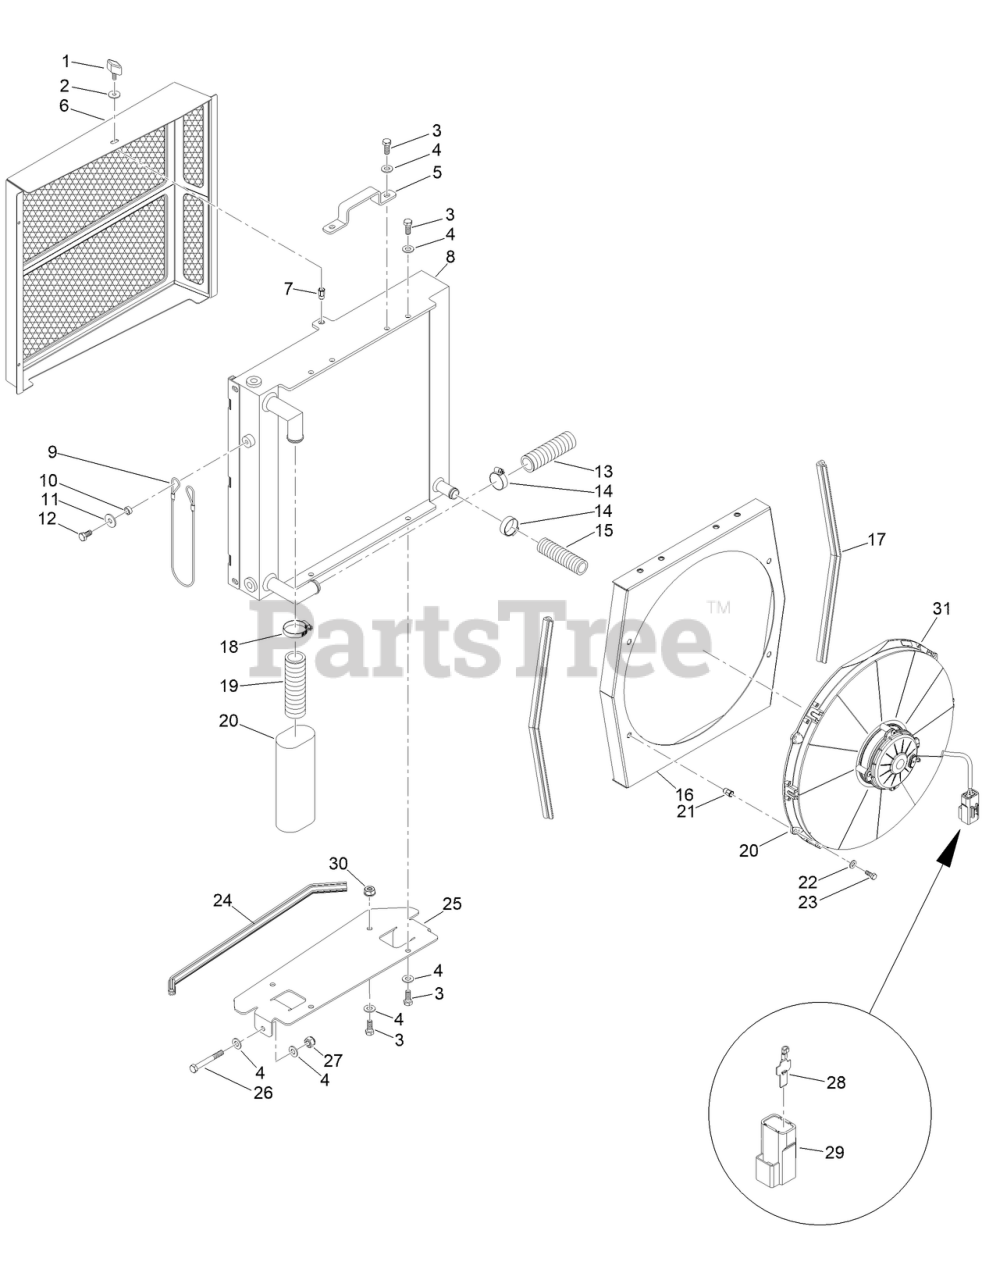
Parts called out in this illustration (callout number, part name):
2	WASHER
4	WASHER
5	BRACKET, RADIATOR HANDLE
6	GRID, RADIATOR
7	INSERT-THREADED
8	RADIATOR
9	CABLE, RADIATOR
10	SPACER
11	WASHER
13	HOSE, RADIATOR
15	HOSE, RADIATOR
16	CONVEYOR, RADIATOR
17	GASKET, MM 410
19	HOSE, RADIATOR 25X1240
20	HOSE GUARD
21	INSERT-THREADED
22	WASHER
24	GASKET, MM 440
25	SUPPORT, RADIATOR
28	CONNECTOR-TERMINAL
29	CONNECTOR-2WAY
31	FAN, RADIATOR
